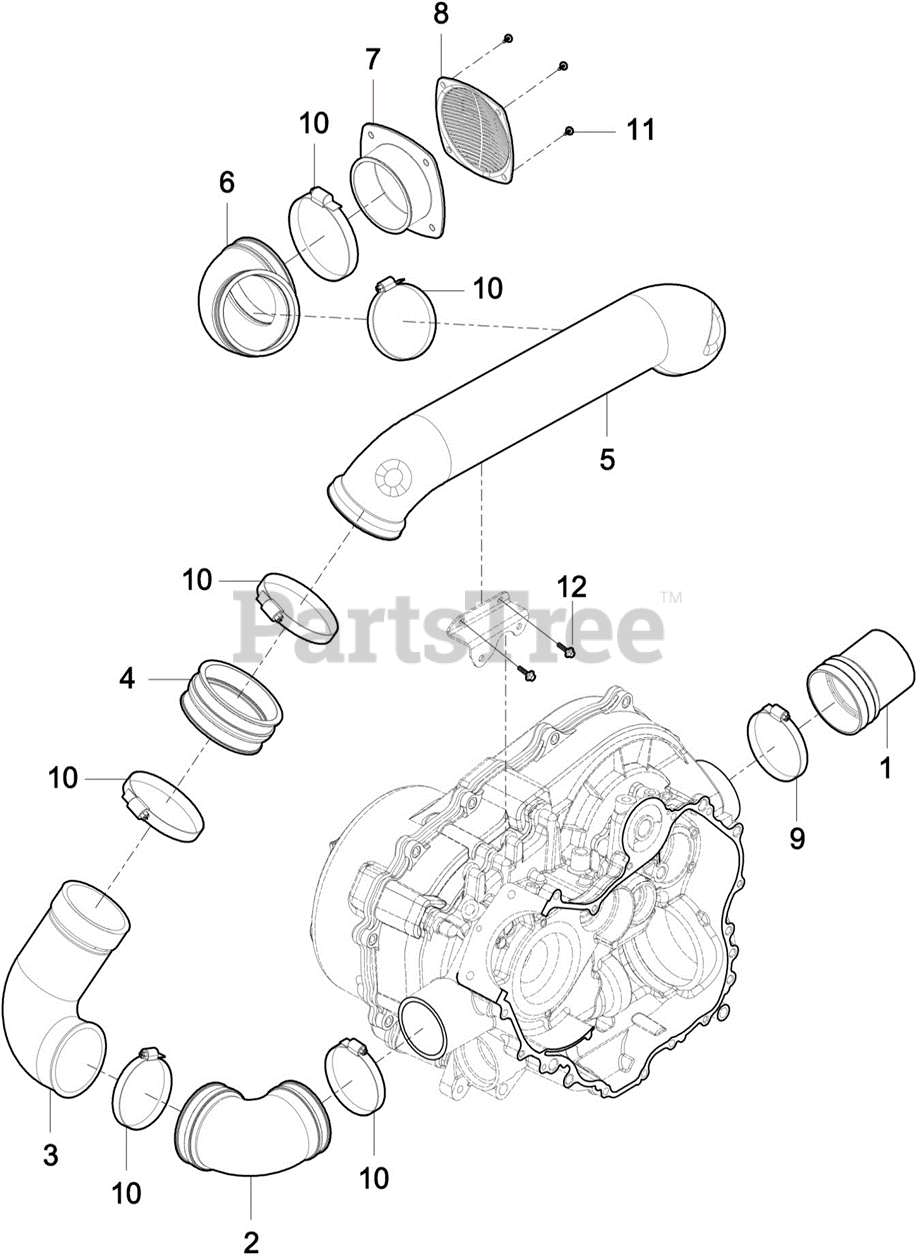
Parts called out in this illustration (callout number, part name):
1	CLUTCH AIR OUTLET SLEEVE
2	CLUTCH AIR INLET SLEEVE
3	CLUTCH AIR INLET DUCT
4	CLUTCH AIR INLET SLEEVE
5	CLUTCH AIR INLET DUCT
6	CLUTCH AIR INLET SLEEVE
7	CLUTCH AIR INLET FLANGE PLATE
9	SCREW HOOP
10	NARROW BAND CLAMP
11	SCREW M6X20 LG PLT HD
12	HEXAGON FLANGE BOLT M6X16
